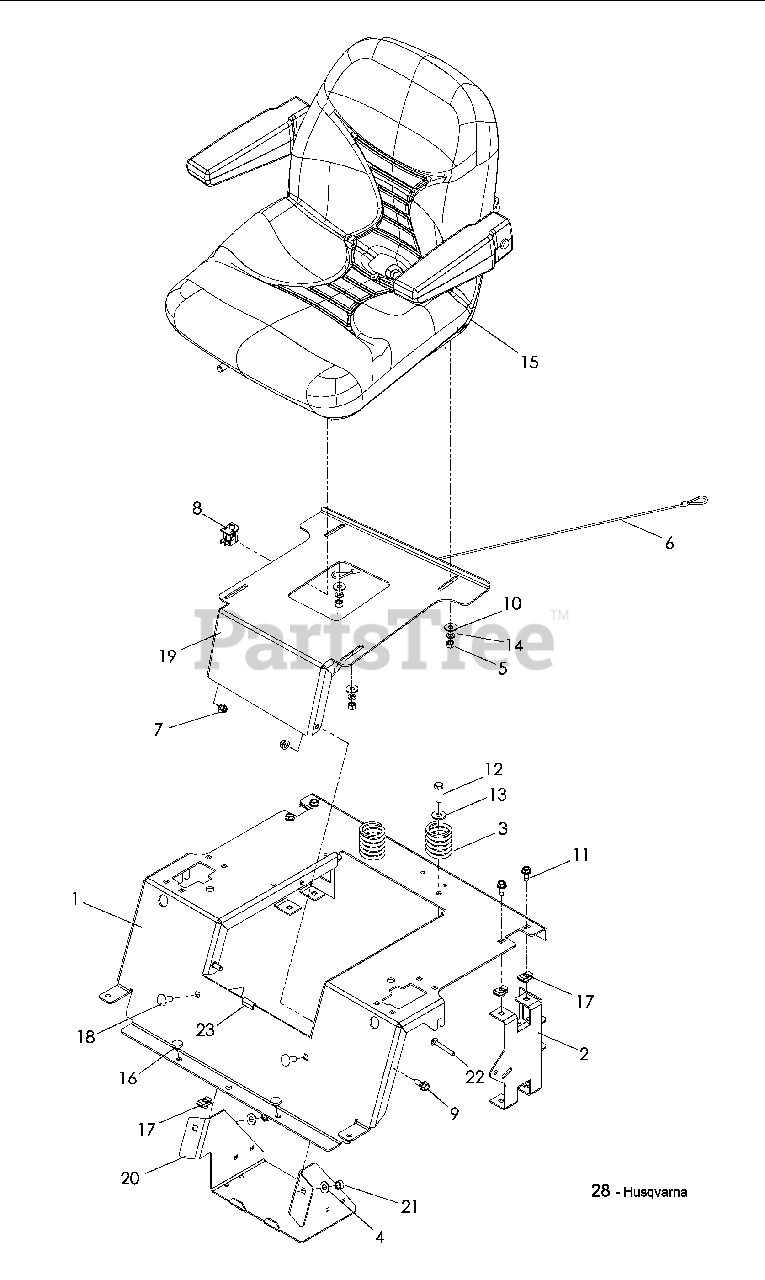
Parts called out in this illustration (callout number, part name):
1	SUPPORT, SEAT
2	SUPPORT, REAR SEAT
3	SPRING, SEAT
4	WASHER 3/8 SAE FLAT
5	NUT 5/16-18 HEX NYLOC
6	LANYARD, SEAT
7	NUT 5/16-18 FLANGE NYLOC
8	SWITCH, SEAT
9	BOLT 5/16-18 HEX HD SHLDR
10	WASHER 5/16 STD FLAT
11	BOLT 5/16-18 x ¾ THD FRM
12	HCS 3/8-16 x 1¼
13	WASHER 3/8 FLAT STD
14	WASHER 5/16 SLW
15	SEAT
16	GROMMET, BUMPER
17	RETAINER, U TYPE
18	RHSNB 3/8-16 x 1
19	PAN, SEAT
20	BOX, BATTERY
21	NUT 3/8-16 HEX NYLOC
22	RHSNB 5/16-18 x 2½
